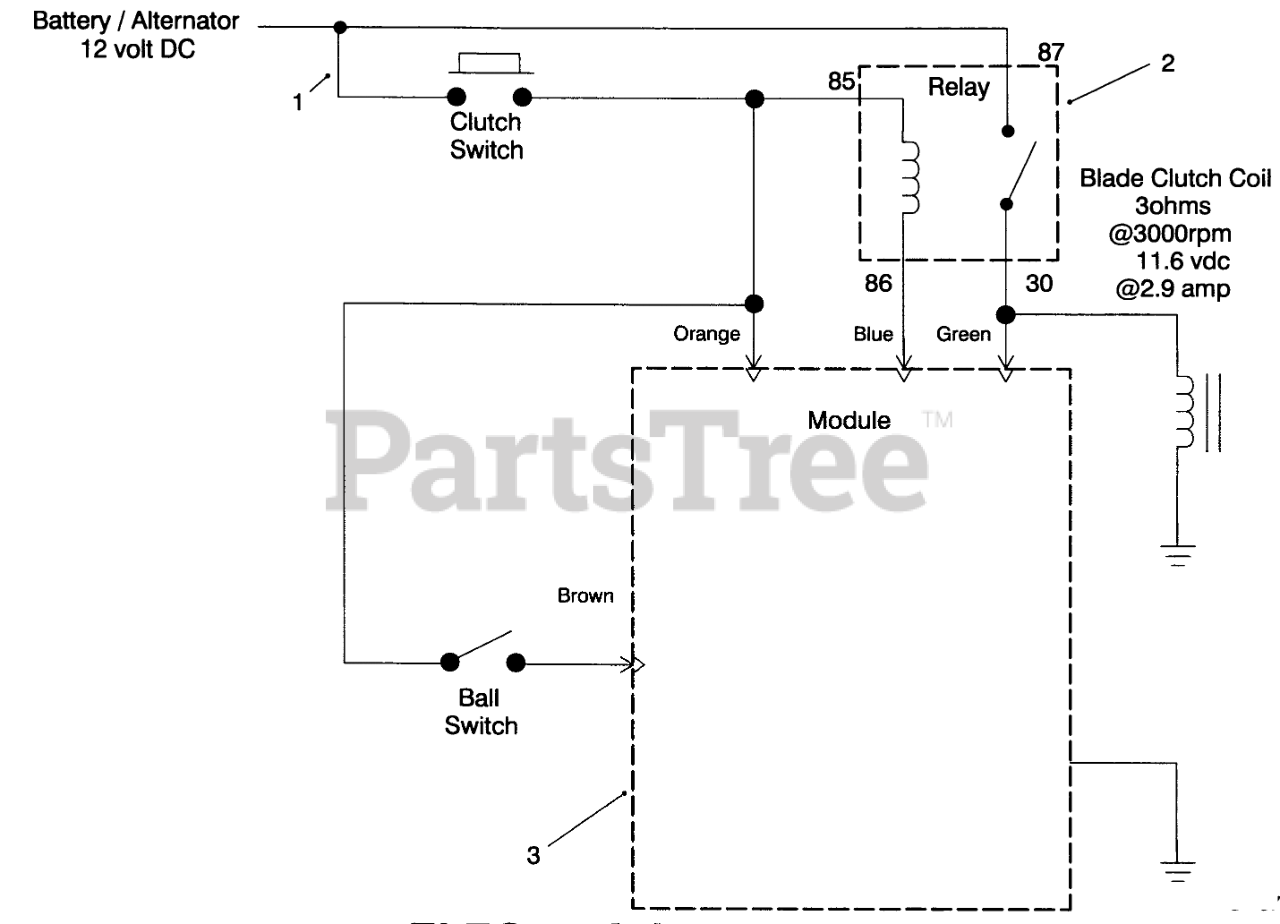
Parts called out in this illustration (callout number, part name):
1	Wire Harness
2	Module
3	RELAY
